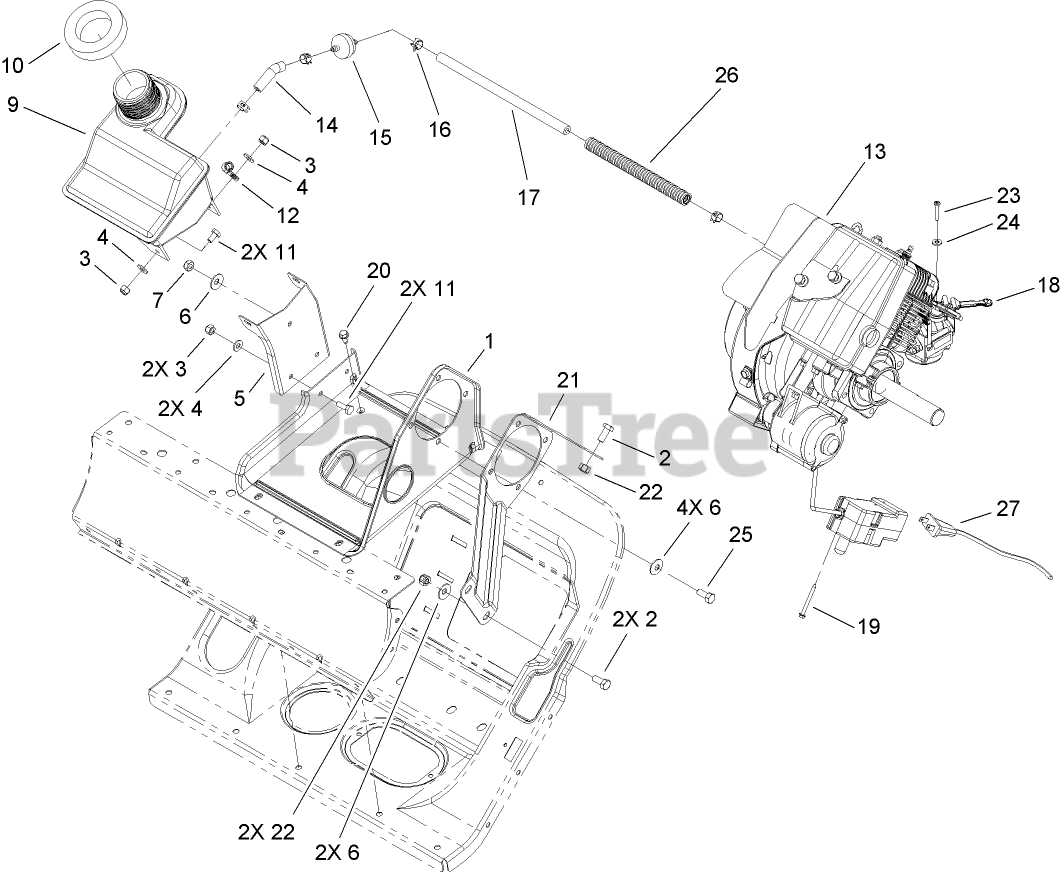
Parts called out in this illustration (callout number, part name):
2	SCREW-HH
3	NUT-LOCK, NI
4	WASHER-FLAT
5	SUPPORT-RECOIL
6	WASHER-BELLEVILLE
7	NUT-LOCK, NI
9	TANK-GAS
10	SEAL-FOAM
11	SCREW-HH
12	CLAMP
13	Loose Parts Package
14	HOSE-FUEL
15	FILTER-FUEL
16	CLAMP-HOSE
17	HOSE-FUEL
18	LEVER-CHOKE
19	SCREW-PLASTITE
20	SCREW-HWH, THREAD ROLL
21	BRACE-ENGINE
22	NUT-LOCK, NI
23	SCREW-PPH, PLASTITE
24	WASHER-FLAT
25	SCREW-HH
26	CONDUIT
27	CORD-ELECTRIC
